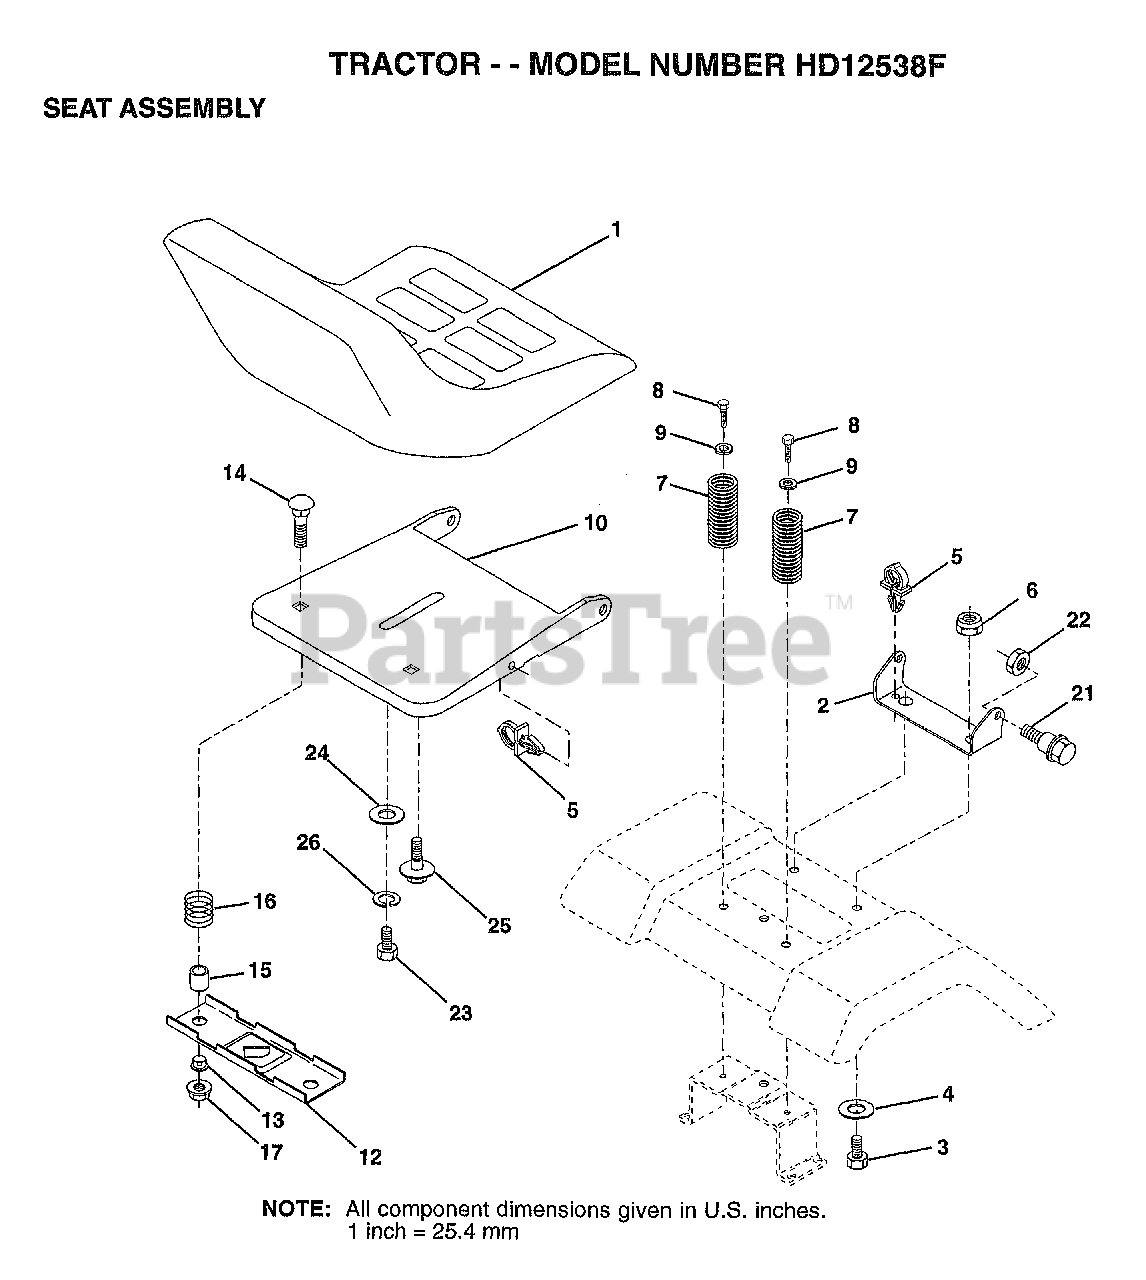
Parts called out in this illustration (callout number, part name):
2	BRACKET PVT SEAT
3	BOLT
4	WASHER PM
5	CLIP.PUSH-IN.HING
6	NUT
7	SPRING COMPRESSIO
8	SCREW GTV
9	WASHER
10	PAN-SEAT
12	BRKT SWITCH
13	BUSHING
14	BOLT-RD HD SQ NK
15	SPLIT SPACER
16	SPRING
21	"BOLT,SHOULDER"
22	NUT
23	BOLT
24	WASHER
25	"BOLT,SHOULDER"
26	LOCKWASHER
